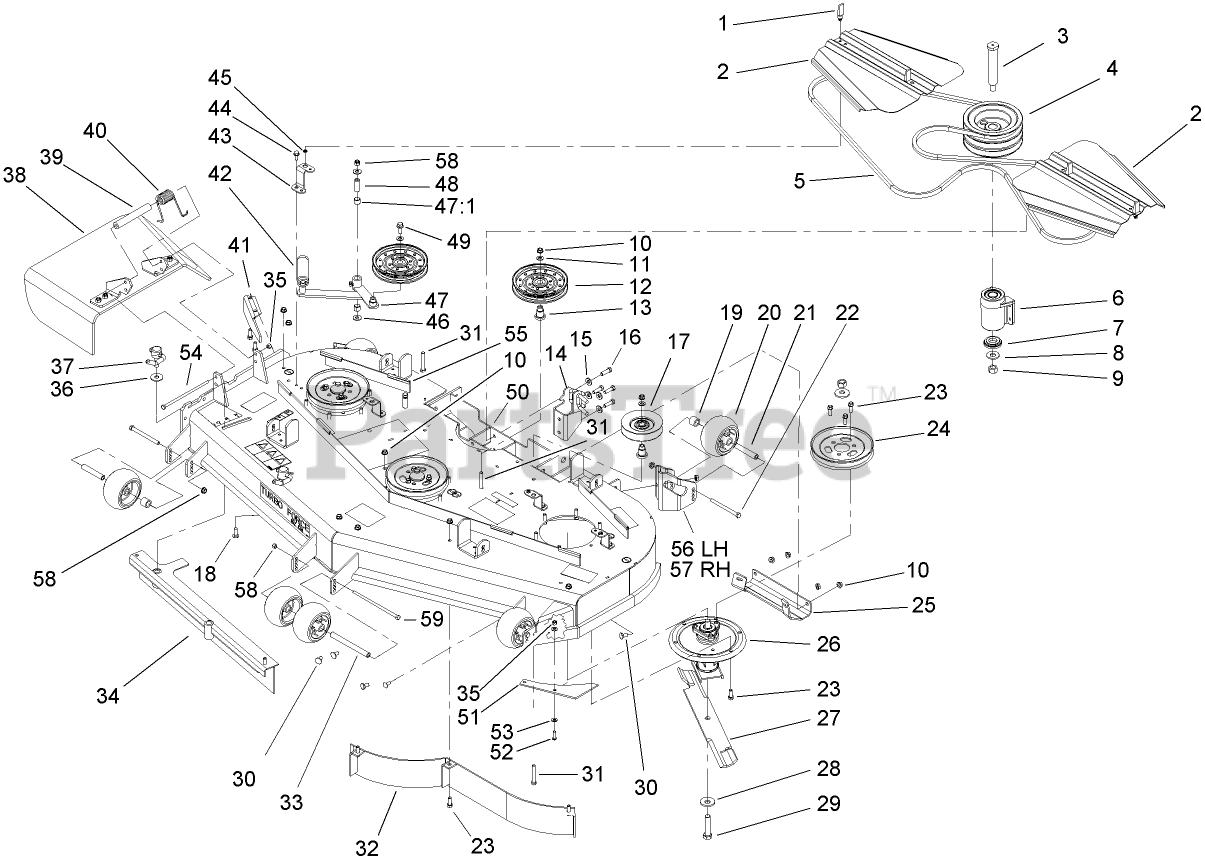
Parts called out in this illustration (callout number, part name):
1	LATCH-SWELL
2	Cover-Belt
3	JACKSHAFT
4	SHEAVE-JACKSHAFT
5	V-BELT-DRIVE, DECK
6	JACKSHAFT ASM
7	SPACER-GUARD, BOTTOM
8	WASHER-SPRING
9	NUT-HEX
10	NUT-HHF, WHIZ
11	WASHER-FLAT
12	Idler-Flat
13	MOUNT-PULLEY
14	GUARD-JACKSHAFT
15	WASHER-BELLEVILLE
16	SCREW-HH
17	PULLEY-IDLER
18	SCREW-CARR
19	TUBE-SPACER
20	ROLLER-SCALP, ANTI
21	TUBE-SPANNER
22	SCREW-HH
23	SCREW-HWH
24	Pulley
25	Plate-Skid
26	Spindle ASM
27	BLADE-HI FLOW
28	Washer-Blade Bolt, Heavy
29	Screw-Cap
30	SCREW-CARR
31	SCREW-HH
33	SPACER-WHEEL
35	NUT-LOCK, NI
36	WASHER-PLASTIC
37	Lever ASM
38	Rubber Deflector ASM
39	SPACER
40	SPRING-TORSION
41	BAFFLE-DISCHARGE
42	SPRING-EXTENSION
43	Bracket-Cover
44	SCREW-HWHTF
45	WASHER
46	WASHER-FLAT
47	IDLER ARM ASM
47:1	SLEEVE-BEARING
48	BUSHING
49	SCREW-HHF
50	DECK DECAL ASM
51	PLATE-TURBO
52	SCREW-HSBH
53	WASHER-SPRING
54	SCREW-HH
55	STRIP-SEAL
56	MOUNT-WHEEL, LH
57	MOUNT-WHEEL, RH
58	NUT-LOCK, NI
59	SCREW-HH
